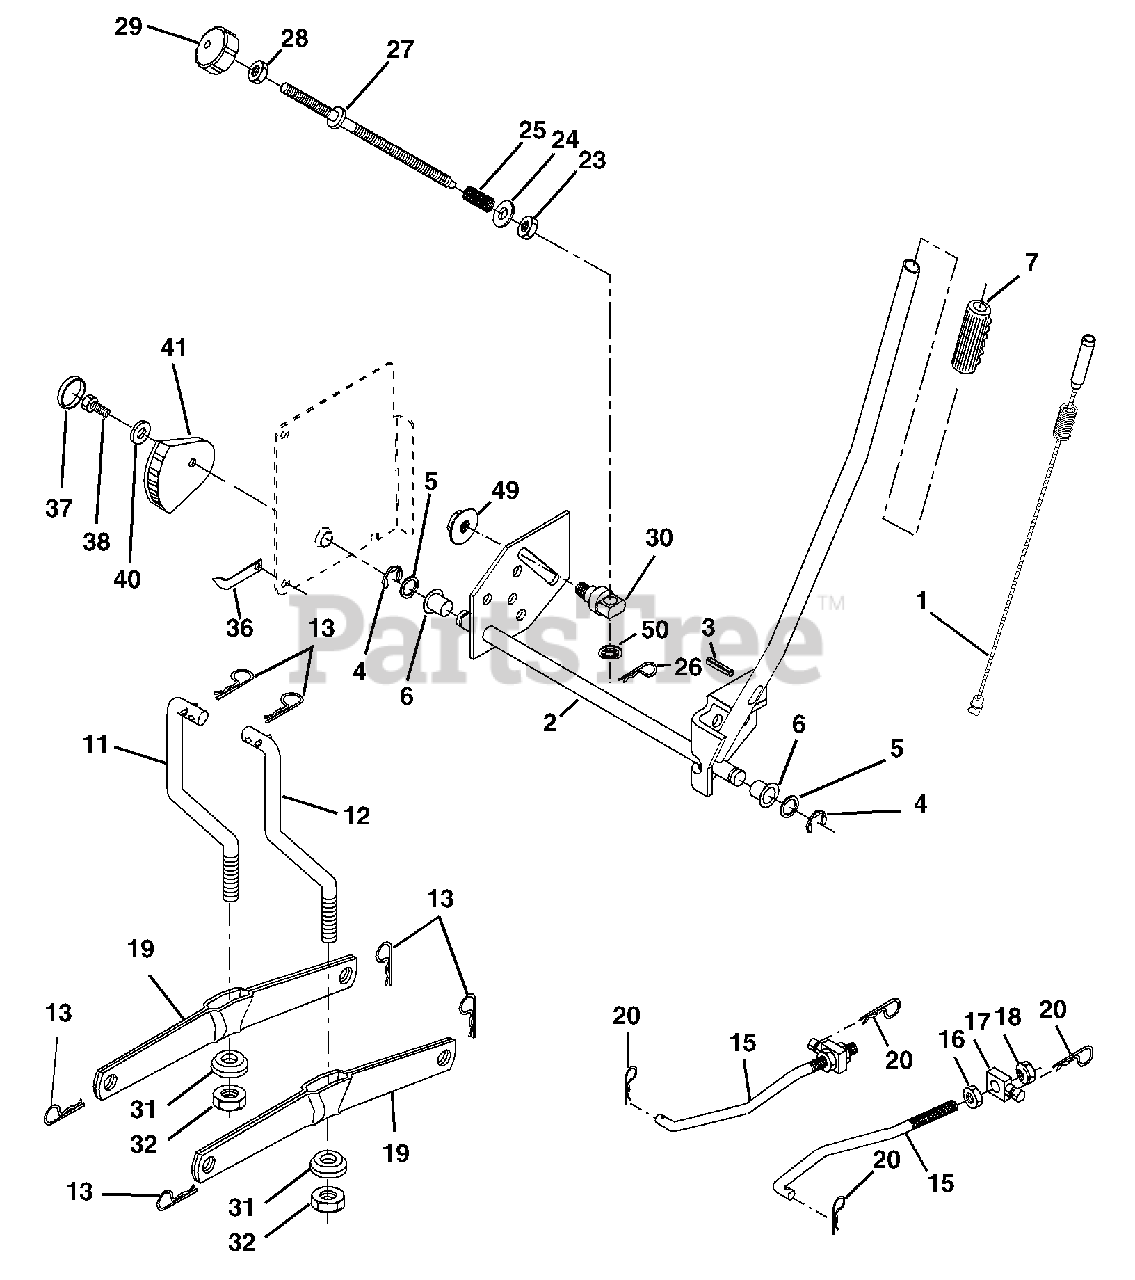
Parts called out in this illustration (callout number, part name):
1	Plunger Asm.
2	Shaft Asm Lift
3	Pin Groove
4	E Ring #5133-62
5	Washer 21/32 x 1 x 21 Ga.
6	Bearing Nylon
7	Grip Handle
11	Link Lift Lh
12	Link Lift Rh
13	Retainer Spring
15	Link Front
16	Nut Jam Hex 1/2-13 Unc
17	Trunnion Blk Zinc
18	Nut Lock w/Wsh 1/2-13 Unc
19	Arm Suspension Rear
20	Retainer Spring
23	Nut Special
24	Washer 13/32 x 5/8 x 16 Ga.
25	Spring
26	Retainer Clip
27	Rod Adj. Lift
28	Nut Hex Jam 3/8-16 Unc
29	Knob
30	Trunnion Infin. Height
31	Bearing Pvt Lift
32	Nut Crownlock 3/8-24
36	Pointer Height Indicator
37	Plug Hole
38	Screw 5/16-18 x 1
40	Washer 11/32 x 1-1/2 10 Ga.
41	Indicator Height
49	Nut Hex Flange Lock
50	Nut Push
